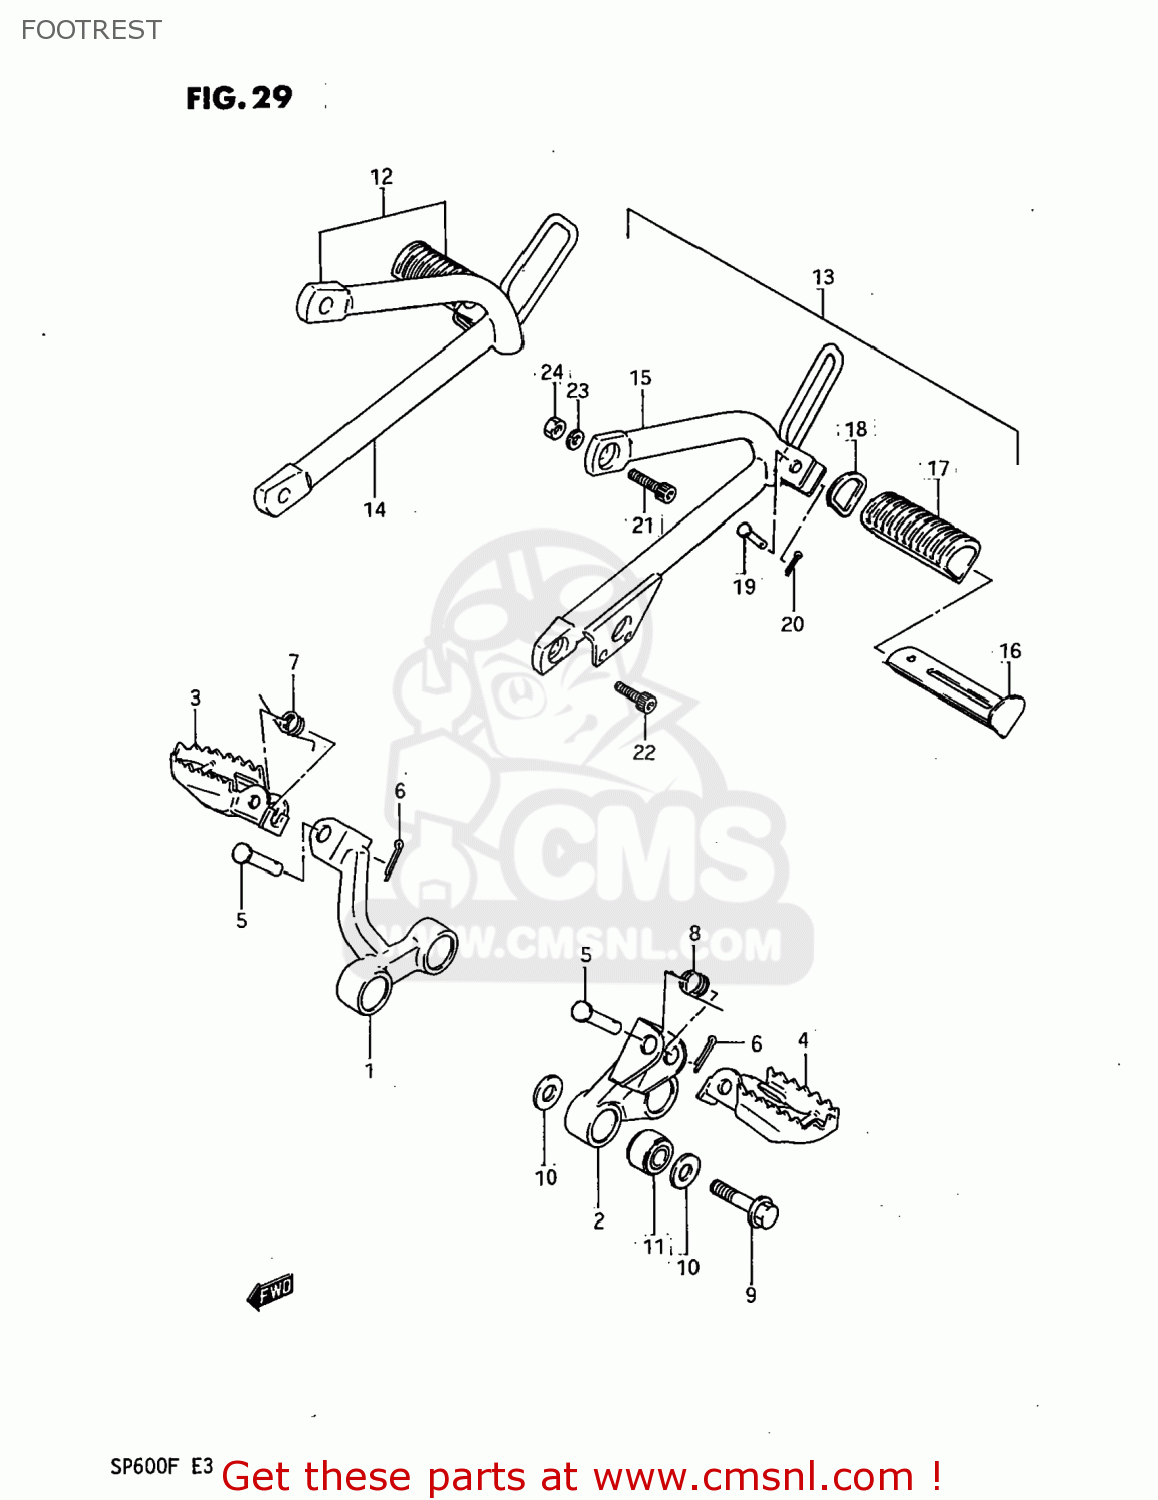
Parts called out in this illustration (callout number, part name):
1	BAR,FR FOOTREST,R
2	BAR,FRONT FOOTREST,LEFT
3	FOOTREST COMP,FRONT,RIGHT
4	FOOTREST
5	PIN
6	PIN 20X20
7	SPRING
8	SPRING
9	BOLT(10X50)
10	WASHER
11	BUSH(10.2X25X19)
12	FOOTREST ASSEMBLY,PILLION
13	FOOTREST ASSEMBLY,PILLION
14	HOLDER,PILLION FOOTREST
15	HOLDER COMP,PILLION FOOTREST
16	BAR COMP,PILLION FOOTREST
17	RUBBER,PILLION FOOTREST
18	WASHER,PILLION FOOTREST
19	PIN
20	PIN
21	BOLT
22	BOLT
23	WASHER,LOCK,8.
24	NUT
